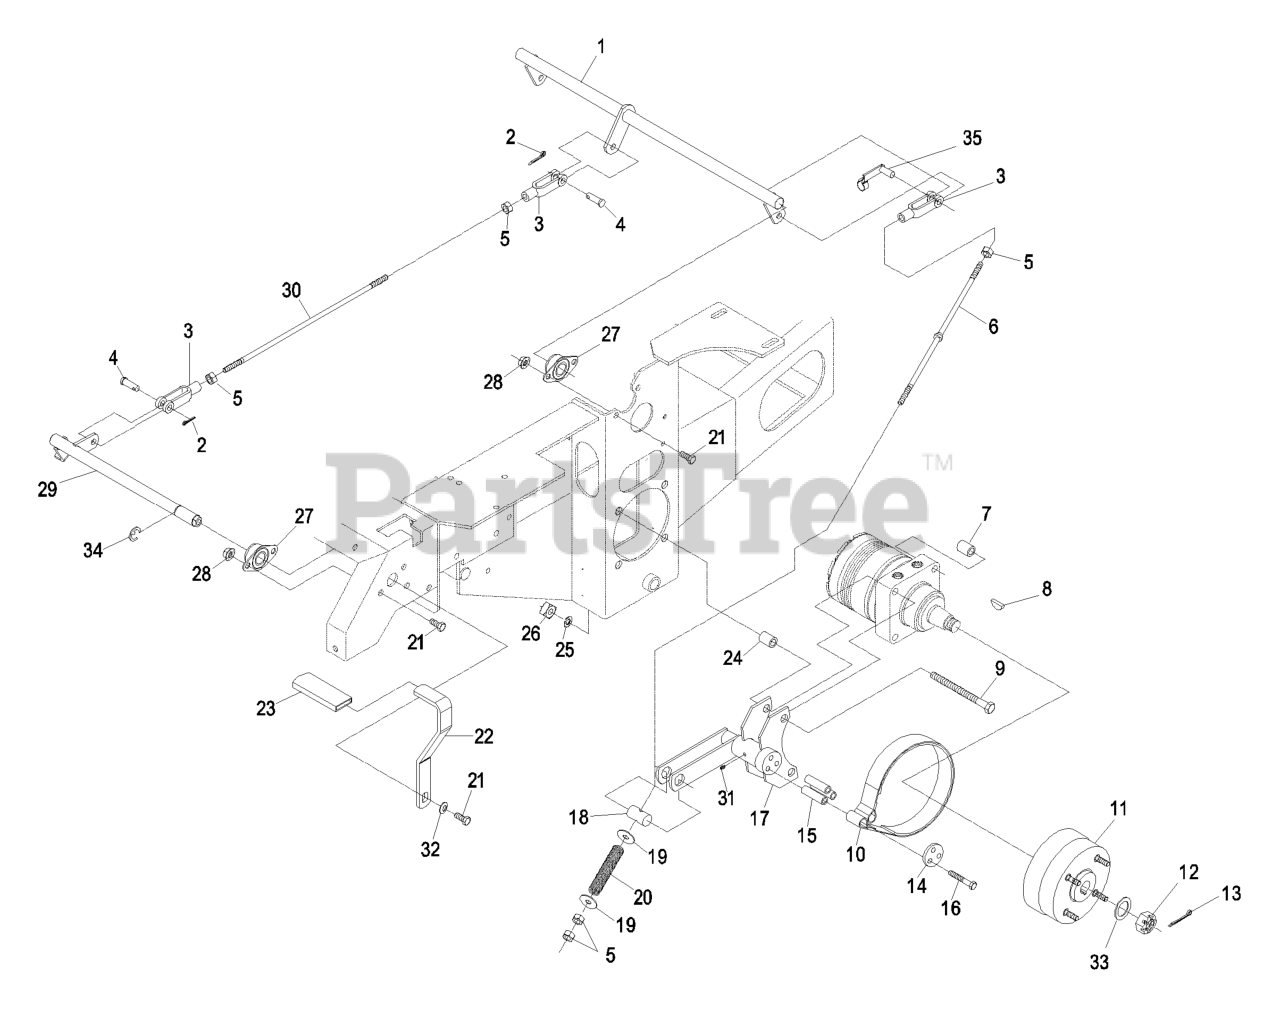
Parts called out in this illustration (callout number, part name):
1	CRANK-BRAKE, PARK
2	PIN-COTTER
3	YOKE-LINKAGE, BRAKE
4	PIN-CLEVIS
5	NUT-HEX
6	ROD-BRAKE
7	SPACER-WHEEL
8	KEY-WOODRUFF
9	SCREW-HH
11	WHEEL HUB ASM
13	PIN-COTTER
14	RETAINER-BAND, BRAKE
16	SCREW-HH
17	BRACKET-BRAKE
18	PIN-TRUNION
19	WASHER-FLAT
20	SPRING-BRAKE
21	SCREW-HH
22	ASM,BRAKE HANDLE W/ GRIP
23	GRIP-LEVER
24	SPACER-WHEEL
25	WASHER-LOCK
27	BEARING-FLANGE, SIDE
28	NUT-HHF, WHIZ
29	SHAFT-BRAKE, PARKING
30	LINKAGE-HANDLE, BRAKE
31	FITTING-GREASE
32	WASHER-BELLEVILLE
33	WASHER-SPACER
35	PIN-SPRING, CLEVIS
